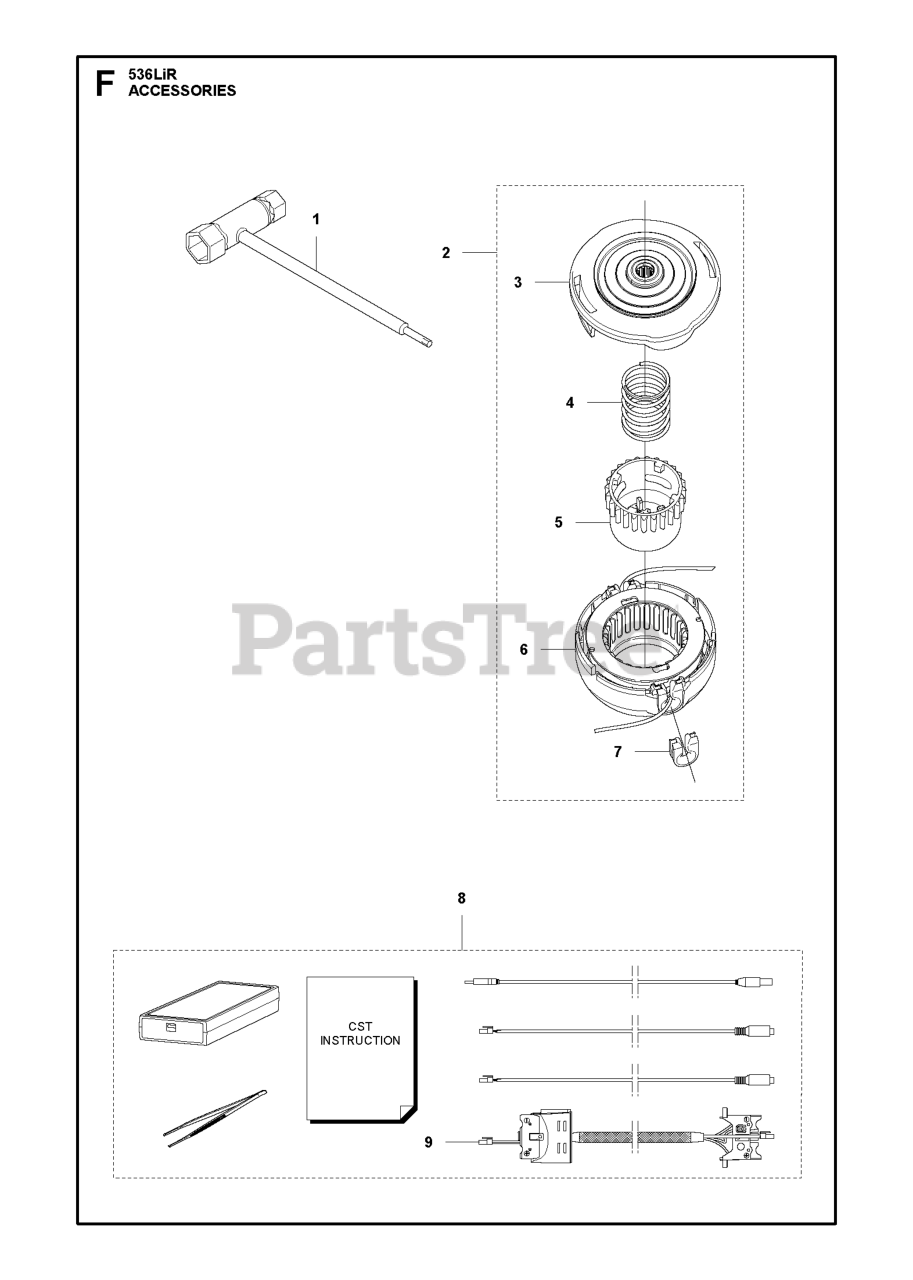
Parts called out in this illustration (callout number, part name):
1	COMB.TOOL 8-10-14
2	RP_T25 TRIMMER HEAD 10MM(BATT
3	HOUSING ASSY
8	DIAGNOSTIC TOOL KIT
9	WIRING ASSY
